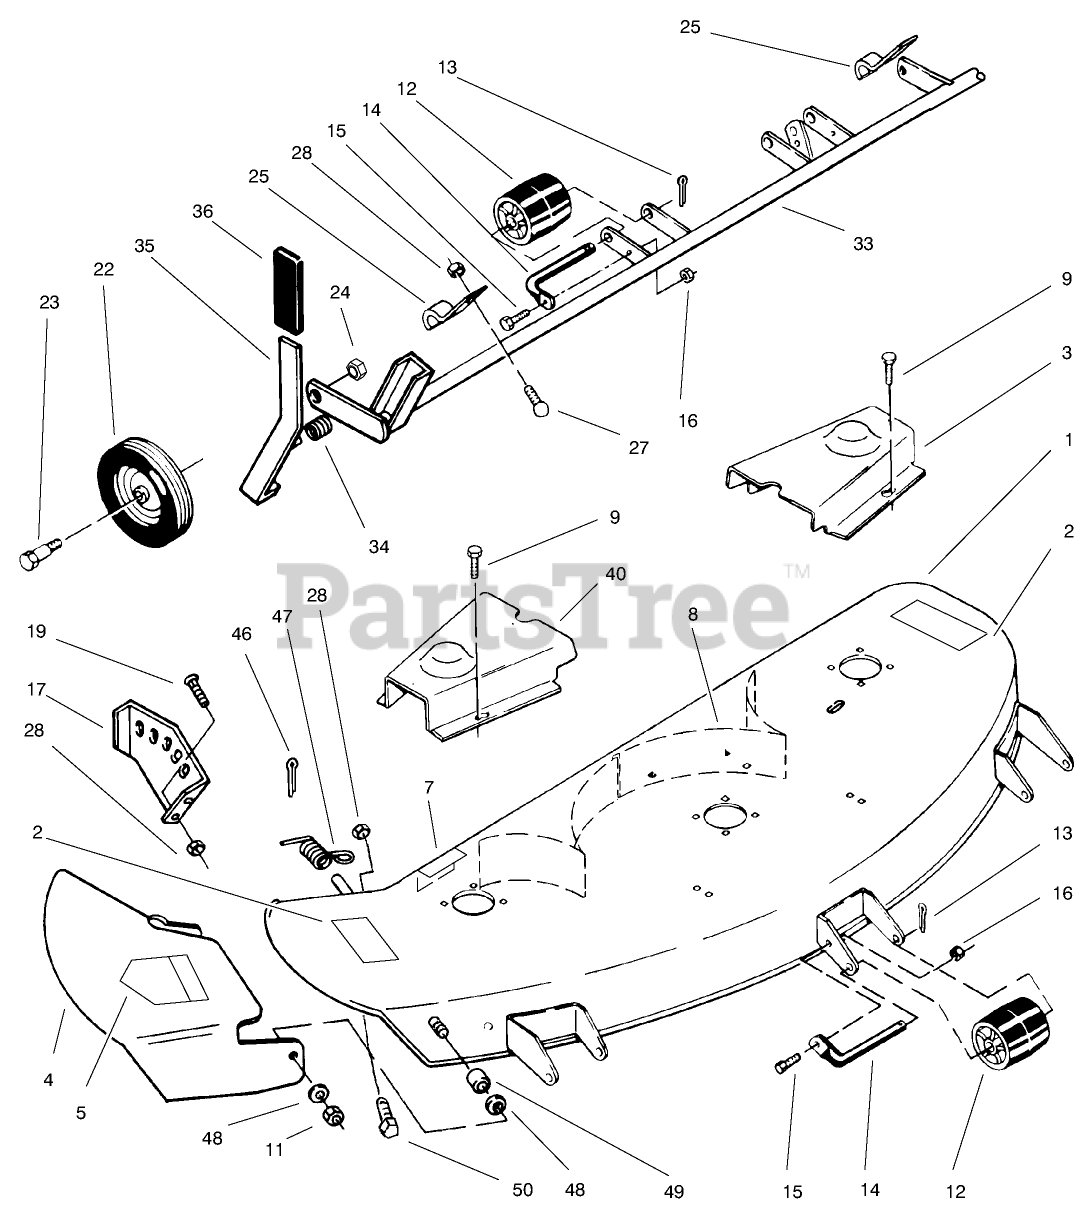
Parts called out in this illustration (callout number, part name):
1	Deck-Assembly (Incl. Ref. #2 & 8)
2	DECAL-DANGER
3	Belt Cover LH
4	Chute Assembly (Incl. Ref. #5)
5	DECAL-DANGER
7	DECAL-HEIGHT & BELT
8	BAFFLE-DECK R.H.
9	SCREW-HWH
12	ROLLER
13	PIN-COTTER
14	ROLLER-SHAFT
15	SCREW-HH
16	NUT-LOCK, NI
17	Quadrant
19	BOLT-CARR
22	WHEEL
23	BOLT-SHOULDER
24	NUT-HEX
25	Clamp
27	BOLT-CARR
28	NUT-LOCK, NI
33	Support-Gage Wheel
34	SPRING-COMPRESSION
35	Lever
40	Belt Cover RH
46	PIN-COTTER
47	SPRING-DEFLECTOR
48	WASHER
49	BUSHING-PIVOT
50	SCREW-HH
